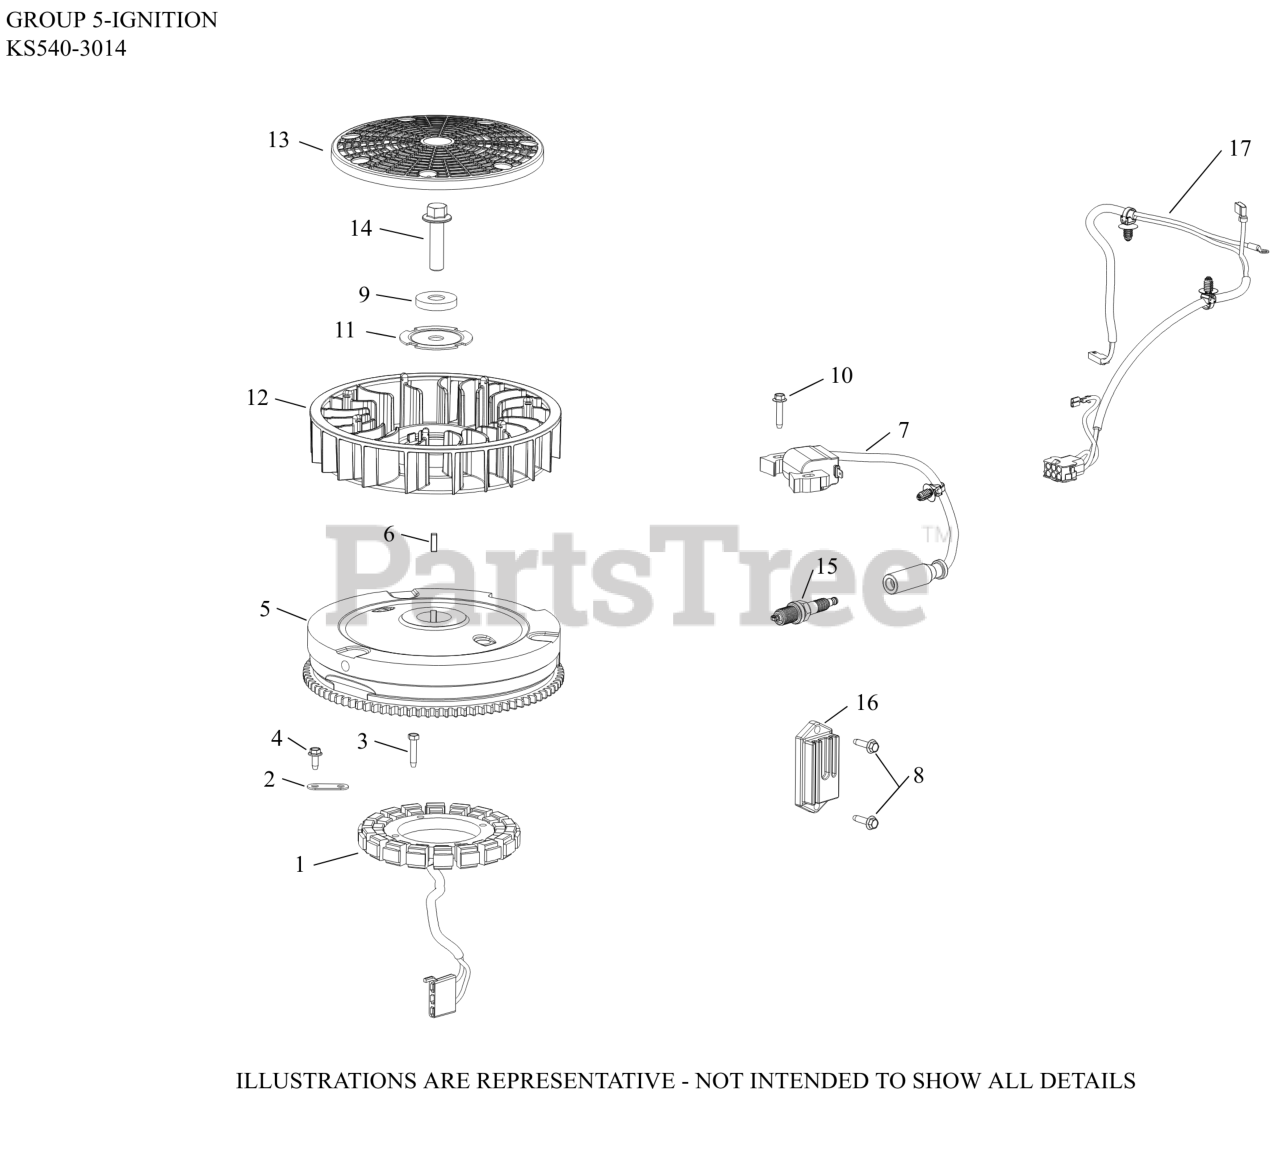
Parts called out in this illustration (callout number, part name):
1	STATOR ASSY, 12A
2	CLIP, STATOR WIRE
3	SCREW, THREAD FORMING
4	SCREW, FLG THD FRM M5X0.8X13
5	FLYWHEEL, ASSY
6	KEY, SQUARE
7	MODULE, INDUCTIVE IGNITION COIL
8	SCREW, THD FRM-USE 25 086 473-S
9	WASHER, FLAT
10	SCREW, THREAD FORMING
11	PLATE, FAN MOUNTING
13	SCREEN, GRASS
14	SCREW, HEX FLANGE
15	PLUG, SPARK
16	REGULATOR/RECTIFIER 12/15A HALF-WAVE STD
17	HARNESS, WIRING NON-OSU, MTD
